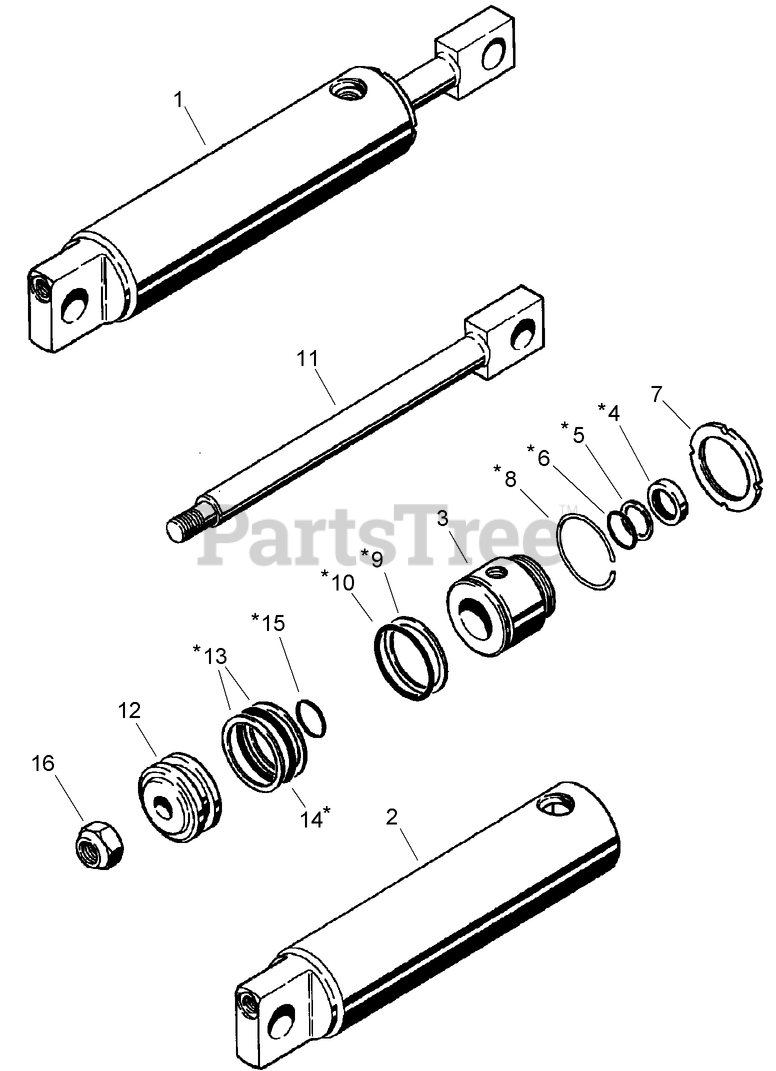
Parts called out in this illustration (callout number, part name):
1	HYD CYLINDER ASM
2	TUBE - Cylinder
3	GLAND - Cylinder
4	WIPER - Rod
5	RING - Backup, O-Ring, Gland Inner, Piston Rod
6	O-RING - 1 ID x 1/8 inch Wide, Gland, Inner, Piston Rod
7	NUT - Gland Locking
8	RING - Retaining
9	RING - Backup, Gland O-Ring, Outer
10	O-RING - 2-1/4 ID x 1/8 inch Wide, Gland, Outer
11	ROD - Piston, 25 mm (1 inch) Diameter
12	PISTON - Cylinder
13	RING - Backup
14	O-RING - 2-1/8 ID x 3/16 inch Wide, Outer
15	O-RING - 1 ID x 1/8 inch Wide, Gland, Inner, Piston Rod
16	NUT-hex, self-locking, 3/4 inch NF
